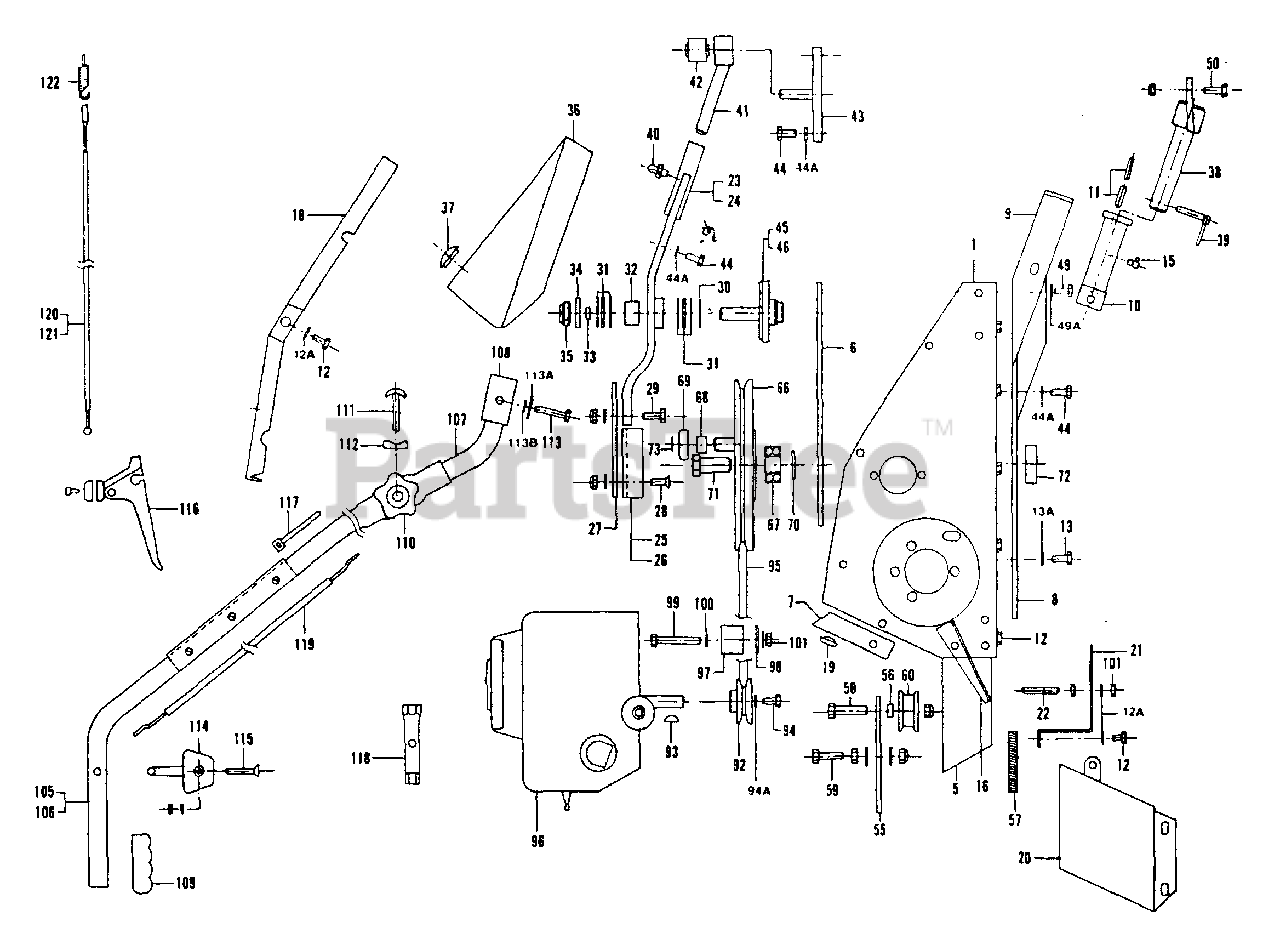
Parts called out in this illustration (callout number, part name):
1	Frame Assembly
5	Plate - Engine Mount
6	Plate - Bottom Reinforcement
7	Frame Hood - Rear
8	Cutter Bar Holder Assembly
9	Cutter Bar Holder Weldment
10	Cutter Bar Holder Kit
11	Roll Pin - 6 x 20
12	Screw - HHM8 x 12
12A	Washer
13	Screw - HHM8 x 16
15	Grease Fitting - 90° M6 x 100
16	Grass Shield - Wheel - RH
18	Hood w/Logo Decal
19	Plastic Plug
20	Cover - Drive Belt
21	Cover - Cutter Bar Belt
22	Rod - Belt Disengagement
24	Drive Arm w/Channel Kit
26	Channel - Drive Arm
27	Plate - Channel Upper
28	Screw w/Nylock Nut & Washer
29	Screw w/Nylock Nut & Washer
31	Thrust Bearing Set
35	Nut - Nylock M18
36	Grass Shield w/Decal
37	Plastic Plug - Grass Shield
38	Mounting Shaft - Cutter Bar
39	Retaining Clip - M8 x 40
40	Grease Fitting - M6 x 100
41	Drive Arm Mounting Shaft
42	Bushing - Sickle Drive
43	Mount - Cutter Bar
44	Screw - HHM8 x 20
44A	Washer
45	Support Plate - Drive Arm Axle
46	Support Plate - Drive Arm Axle
49	Screw - HHM8 x 25
50	Screw - HHM8 x 25 & Nylock Nut
55	Clutch Plate
56	Bushing - Idler
57	Spring - Blade Engagement
58	Screw - HHM12 x 45 & Nylock Nut
59	Bolt - HHM10 x 35 & Nylon Nut & Washer
66	Flywheel Blade w/Bearing
67	Flywheel Blade w/Bearing
68	Bushing - Flywheel
69	Convex Bearing
70	Washer - Flywheel
71	Screw - M20 - Flywheel
72	Nut - Flywheel
73	Circlip - Flywheel
92	Pulley - Cutter Bar
93	Key - Woodruff (Engine Pulley)
94	Screw - HH
95	V-Belt - Cutter Bar
96	Engine - 3.5HP Briggs & Stratton
97	Spacer/Idler
99	Screw - HHM8 x 70
100	Washer
101	Nut - Hex 8 & Washer
105	Handlebar w/Decals/Grips
106	Upper Handlebars - w/Decals/Grips
107	Lower Handlebars
108	Rubber Tube - Handlebar
109	Grip - Handlebar
110	Knob - Handlebar
111	Bolt - Handlebar
112	Lock Clamp - Handlebar
113	Screw - HHM8 x 55
113A	Washer
113B	Washer
114	Throttle Control w/Decal
115	Screw M6 x 45 & Nylock Nut & Washer
116	Handlebar Lever - Control
117	Tie Strap/Tie
118	Wrench - Spark Plug
119	Throttle Cable
120	Cable - Cutter Bar
121	Cable - Wheel Drive
122	Spring - Cable - Wheel Drive
